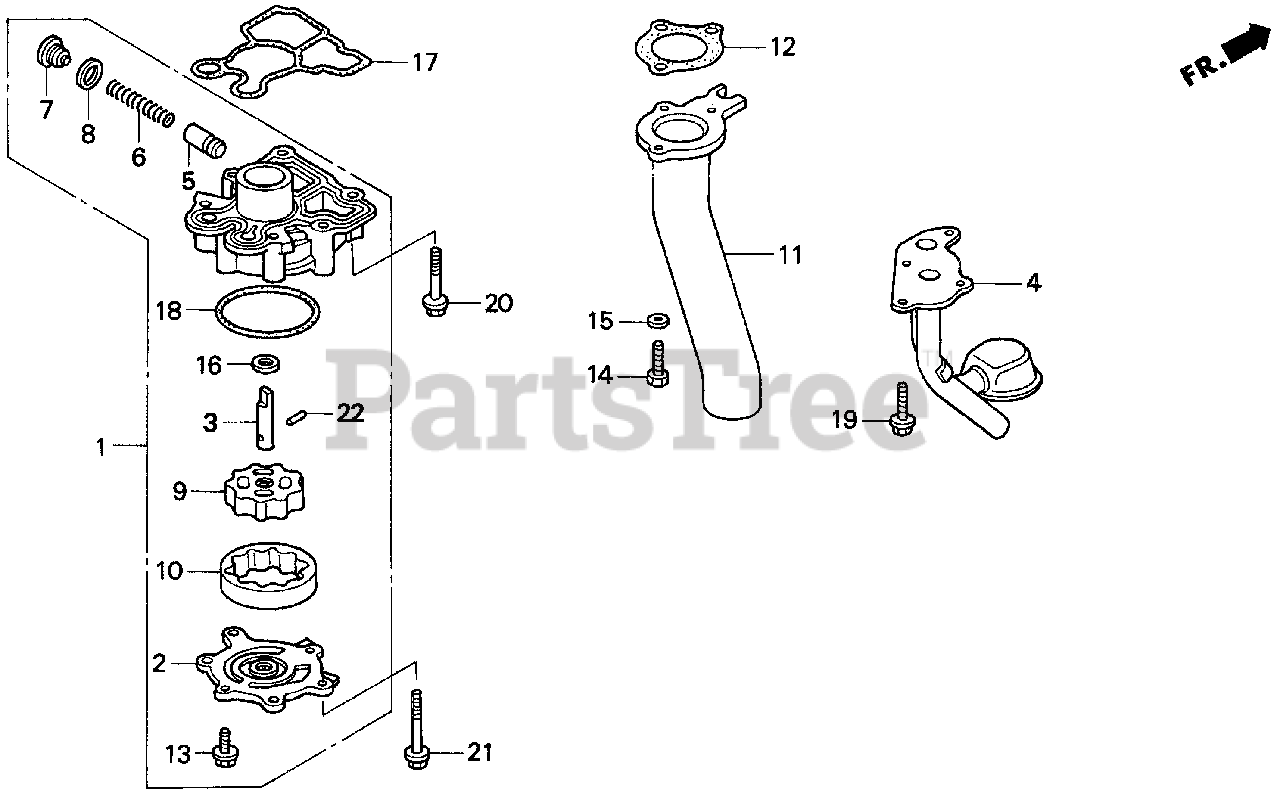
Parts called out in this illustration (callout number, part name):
1	PUMP ASSY., OIL
2	COVER, OIL PUMP
3	SHAFT, OIL PUMP
4	STRAINER, OIL
5	VALVE, RELIEF
6	SPRING, RELIEF VALVE
7	BOLT, SEALING (18MM)
8	WASHER, SEALING (18MM)
9	ROTOR (INNER)
10	ROTOR (OUTER)
12	GASKET, EX. PIPE
13	BOLT, FLANGE (6X18)
14	BOLT, HEX. (8X25)
15	WASHER, PLAIN (8MM)
16	WASHER, THRUST (12MM)
17	O-RING, OIL PUMP
18	O-RING, PUMP COVER
19	BOLT, FLANGE (8X20)
20	BOLT, FLANGE (8X40)
21	BOLT, FLANGE (8X65)
22	ROLLER (5X17.8)
